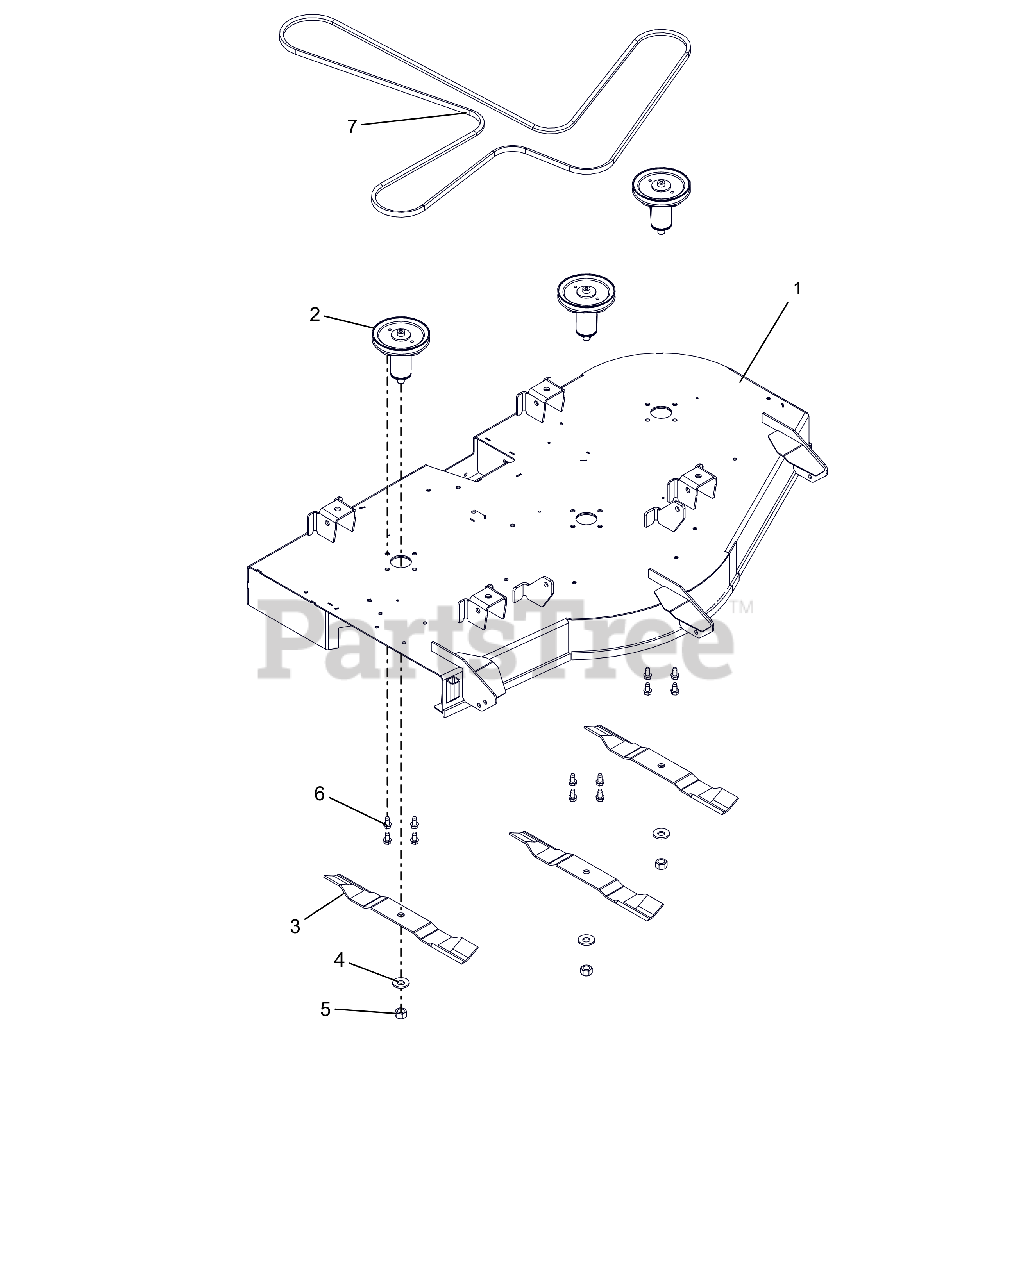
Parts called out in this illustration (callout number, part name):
1	KIT, 52" ARIENS DECK W/DECALS
2	KIT, DECK SPINDLE ASM-52
3	BLADE, 18" - 30 DEG .5 OFFSET
4	WSHR-BLVL .669X1.535X.138
5	NUT-STD .625-18 ZCC
6	SCR,TAP .375-16X.75 HWH TR ZCC
7	V-BELT, HA-WRAPPED
